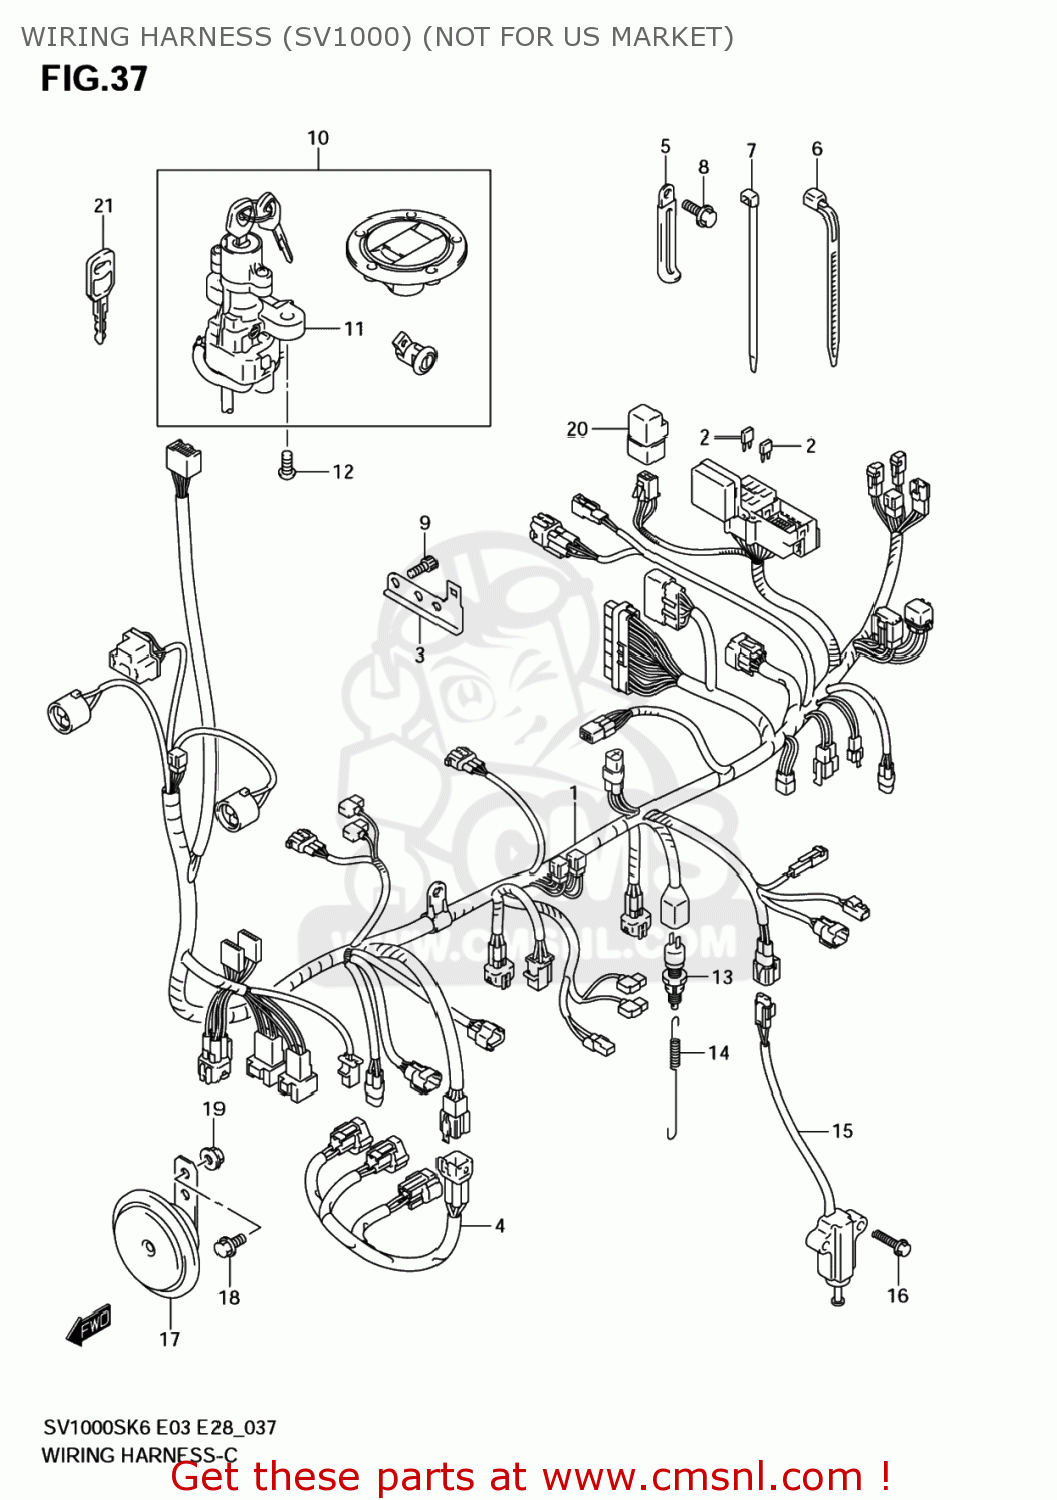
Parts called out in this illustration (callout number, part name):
1	HARNESS,WIRING
2	FUSE(10A)
3	HOLDER,COUPLER
4	WIRE,INJECTOR LEAD
5	CLAMP(L:45)
6	CLAMP(L:95)
7	CLAMP(L:145)
8	BOLT
9	BOLT
10	LOCK SET
11	LOCK ASSY,STEERING
12	BOLT(8X20)
13	SWITCH ASSY,STOP LAMP
14	SPRING
15	SWITCH ASSY,SIDE STAND
16	BOLT
17	HORN ASSY
18	BOLT
19	NUT
20	RELAY ASSY
21	KEY,BLANK
